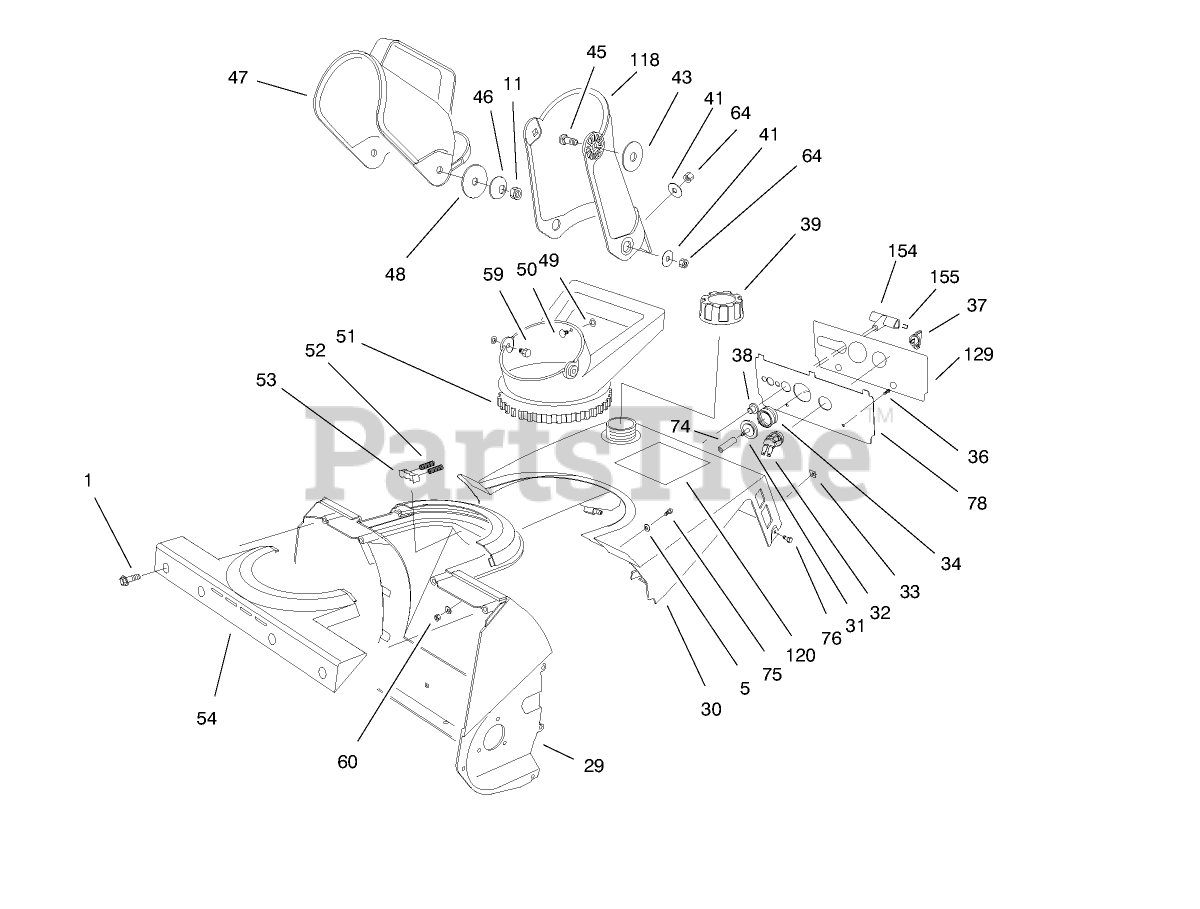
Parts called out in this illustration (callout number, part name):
1	SCREW-PLASTIC
5	WASHER-FLAT
11	NUT-LOCK, NI
29	HOUSING
31	BODY-PRIMER
32	SWITCH
34	BULB-PRIMER
36	SCREW-SHWH, THREAD FORMING
37	KEY-IGNITION
38	GUIDE-ROPE, STARTER
41	WASHER-FLAT
45	BOLT-CARR
46	WASHER-BELLEVILLE
47	DEFLECTOR-CHUTE
48	WASHER-FLAT
49	PUSHNUT-RETAINER, BOLT
50	SCREW-CARR
51	HANDLE-CHUTE
52	SPRING-COMPRESSION
53	DETENT-CHUTE
54	RETAINER-CHUTE
59	SCREW-HH
60	NUT-LOCK, NI
64	NUT-LOCK, NI
74	HOSE-PRIMER
75	SCREW-PPH
76	SCREW-THREAD FORMING
120	DECAL - POWERLITE EL.
154	HANDLE-STARTER
155	STAPLE-HANDLE
